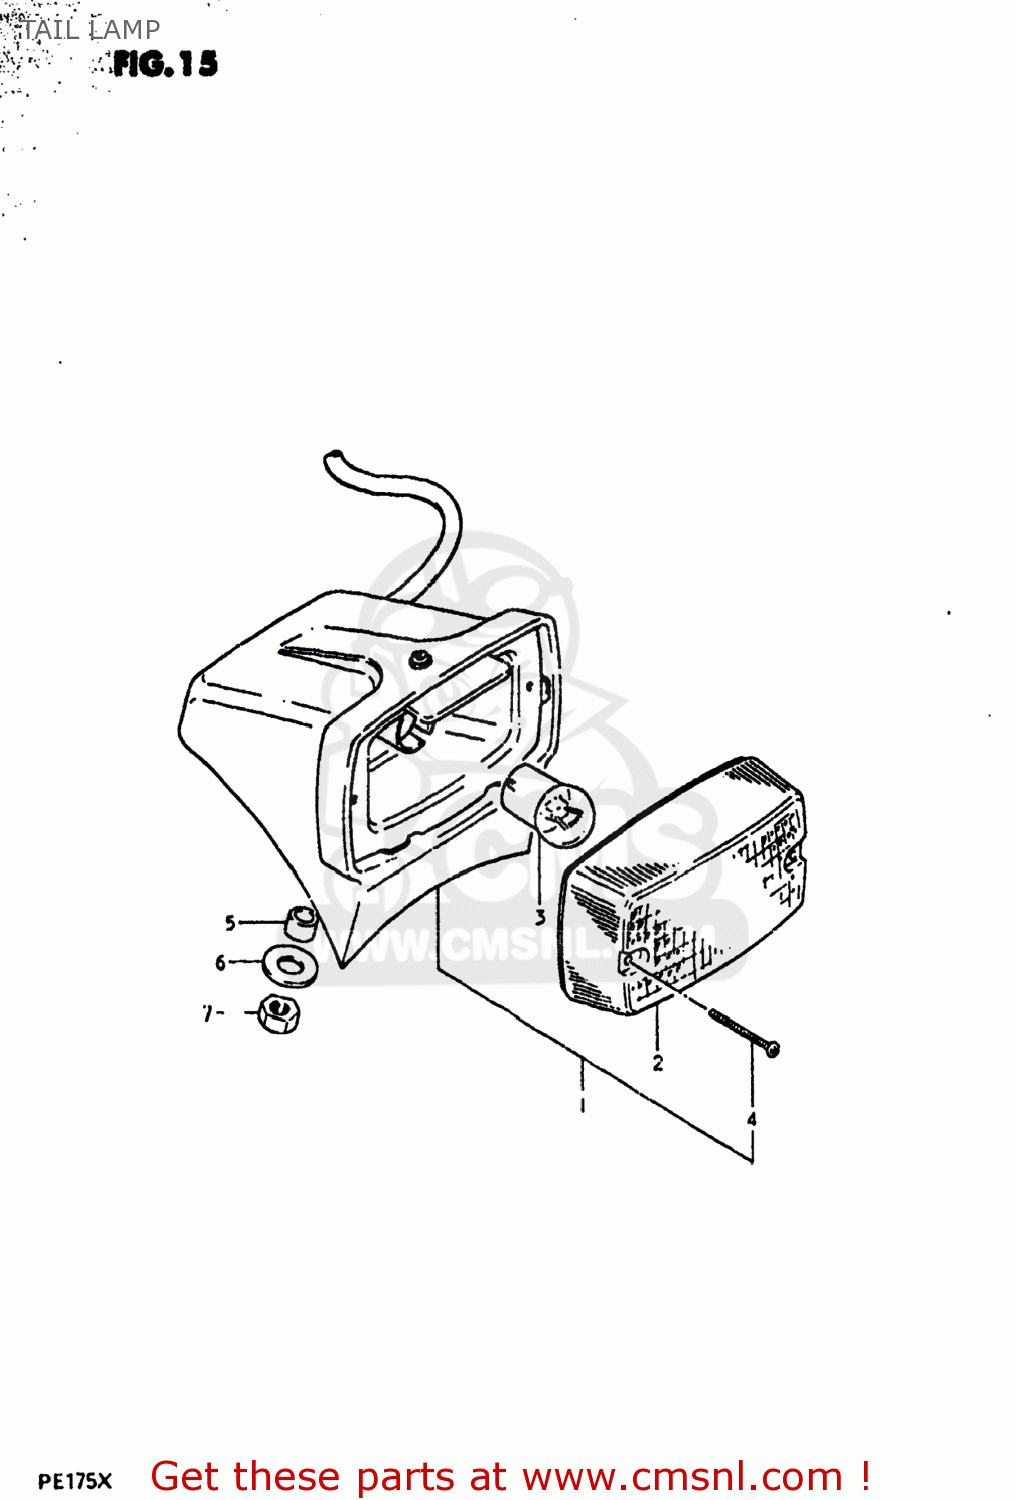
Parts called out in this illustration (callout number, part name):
1	LAMP ASSEMBLY,REAR COMBINATION
2	LENS
3	BULB(6V5W,TOKAI DENSO)
4	SCREW,REAR COMBINATION LAMP LENS
5	SPACER (6.1X9X9)
6	WASHER
7	NUT
